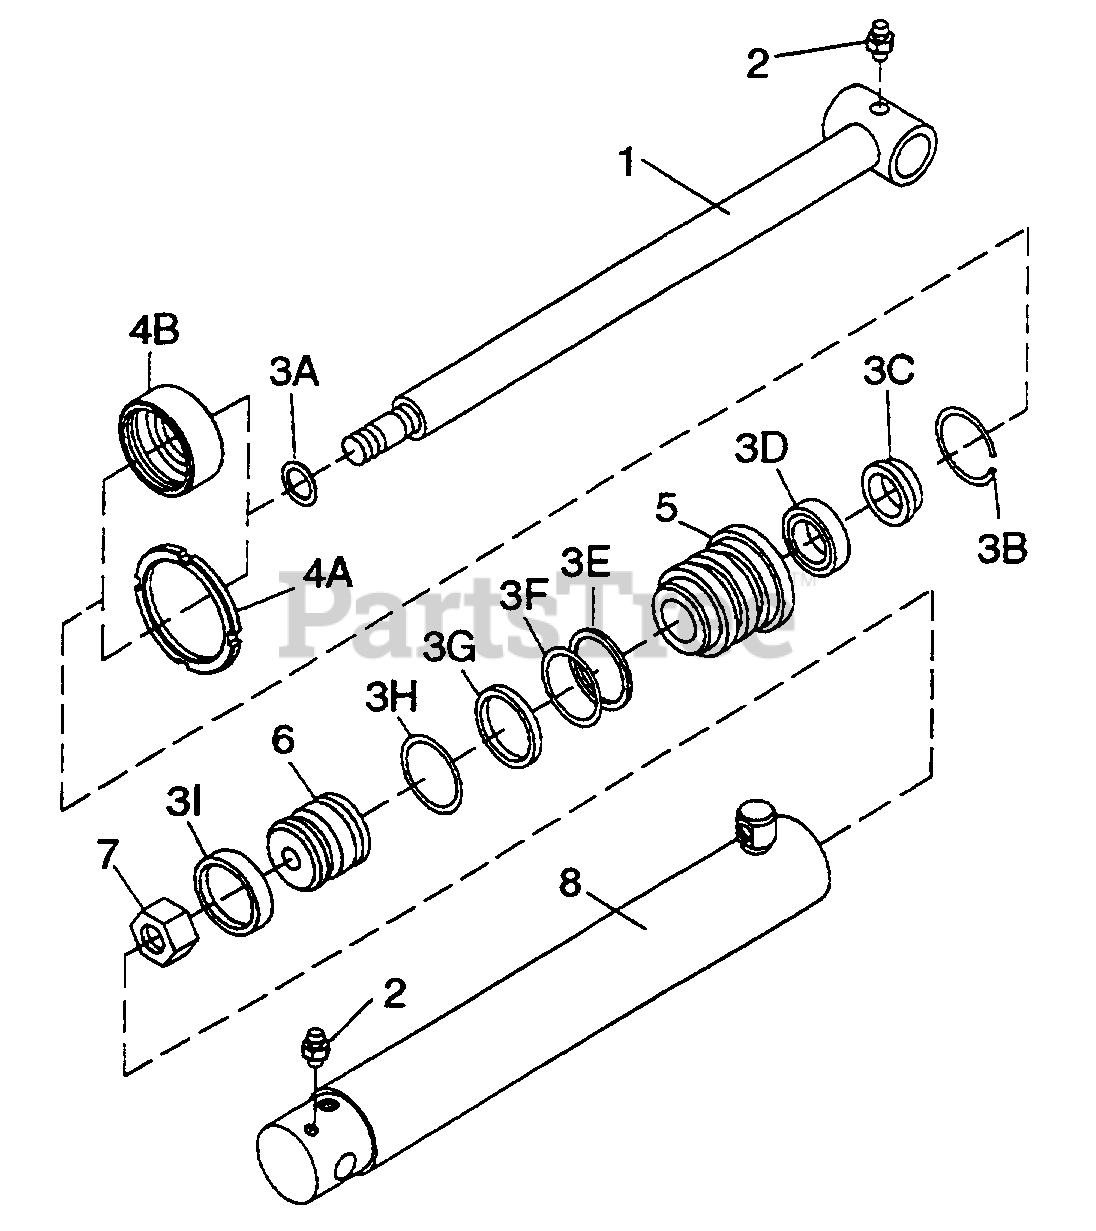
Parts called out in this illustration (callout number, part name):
1	Piston rod, 1-1/8 diameter
2	Grease fitting, 1/4-28 tapered thread
3A	O-Ring, 3/4 ID x 7/8 OD
3B	Round retaining ring, 2" internal
3D	U-Cup, 1-1/8 ID x 1-1/2 OD x 5/16 deep
3E	Back-up washer, 1-3/4 ID x 2 OD
3F	O-Ring, 1-3/4 ID x 2 OD
3G	Piston ring, Teflon 2 OD
3H	O-Ring, 1-9/16 ID x 1-3/4 OD
3I	Wear ring, 2 OD x 1/2 wide X 1/8 thick
4A	Spanner nut, .250 x 2.375 OD
4B	2" Hydraulic cylinder collar
5	Rod guide, 1-5/8 x 2 diameter
5	Rod guide, 1-7/8 x 2 diameter
6	Piston, 2 OD
7	7/8 NF Self-lock hex nut
8	Cylinder barrel, 2 ID
